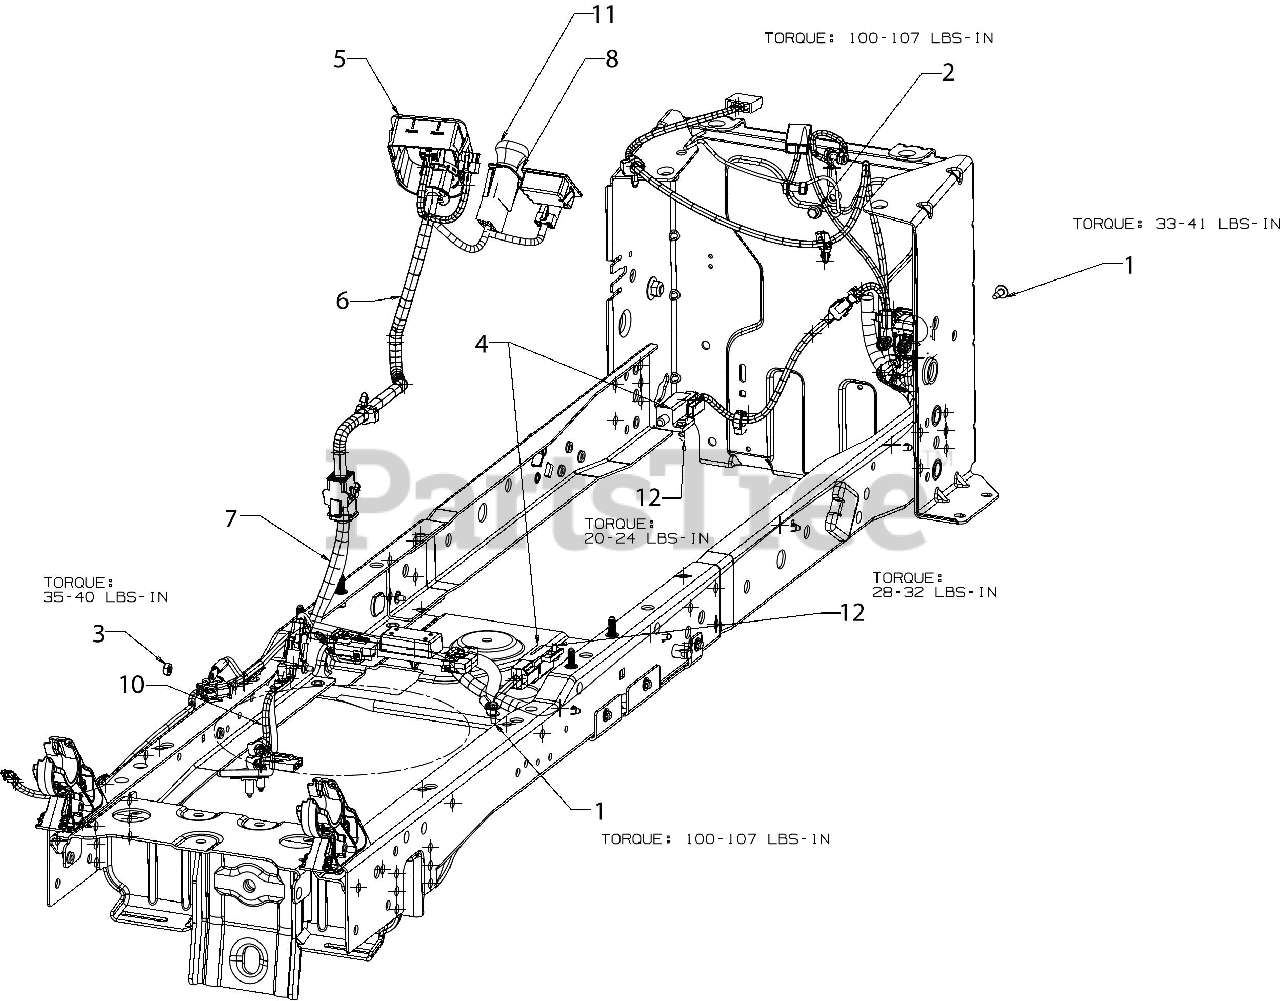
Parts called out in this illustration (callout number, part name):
1	SCREW M6-1 x .625
2	SCREW 1/4-20X.625
3	HEX NUT 1/4-20
4	INTERLOCK SWITCH (NO/NC)
5	IGNITION MODULE SWITCH RMC (ELC PTO WHTE)
6	DASH HARNESS
7	MAIN HARNESS E-PTO/RMC/EPS
8	HOUR METER
9	REVERSE HARNESS
10	CLUTCH HARNESS 11"
11	PTO SWITCH (YELLOW KNOB)
12	SHOULDER SCREW
